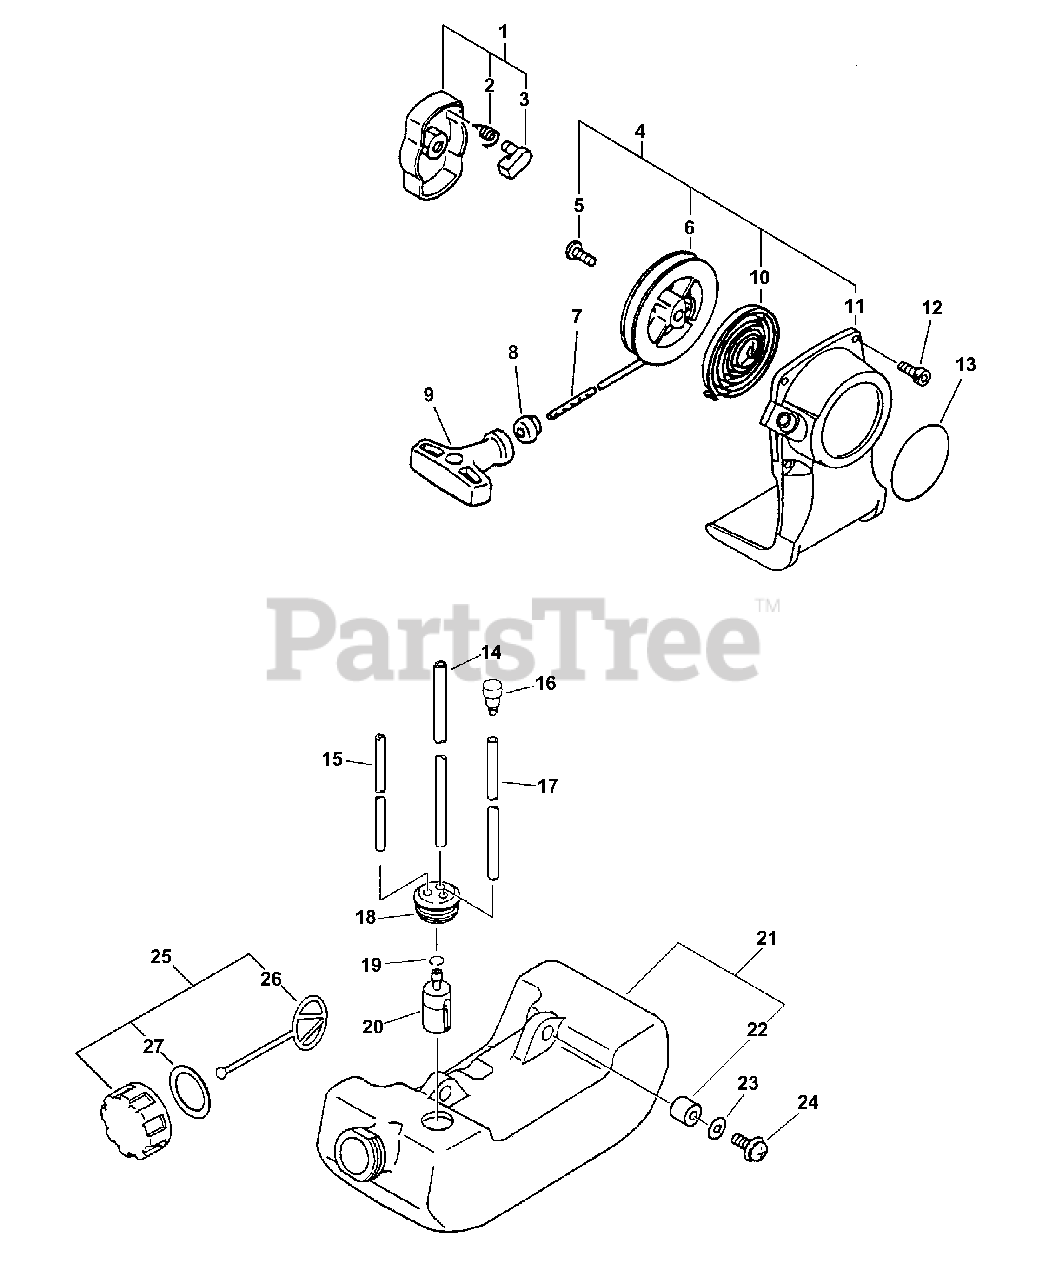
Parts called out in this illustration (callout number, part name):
1	PAWL ASSY, STARTER
2	SPRING, RETURN
3	PAWL, STARTER - BLACK
4	STARTER ASSY
5	SCREW
6	REEL, ROPE
7	ROPE, STARTER 3.0×1000
8	GUIDE, ROPE
9	GRIP, STARTER
10	SPRING, RECOIL
11	CASE, RECOIL STARTER
12	SCREW 4×22
13	LABEL, ECHO
14	PIPE, FUEL 3x-5x-180
15	PIPE, FUEL RETURN 3×6×90 MM CLEAR
16	VENT ASSY
17	PIPE, FUEL 3x-5x-70 BLACK
18	GROMMET, FUEL
19	CLIP 6 MM
20	FILTER, FUEL
21	TANK, FUEL
22	SPACER 6.2×7.8×6
23	WASHER 5.5×12×0.8
24	SCREW 5×16
25	CAP ASSY, FUEL
26	CONNECTOR, CAP L= 100 MM
27	GASKET, FUEL CAP
